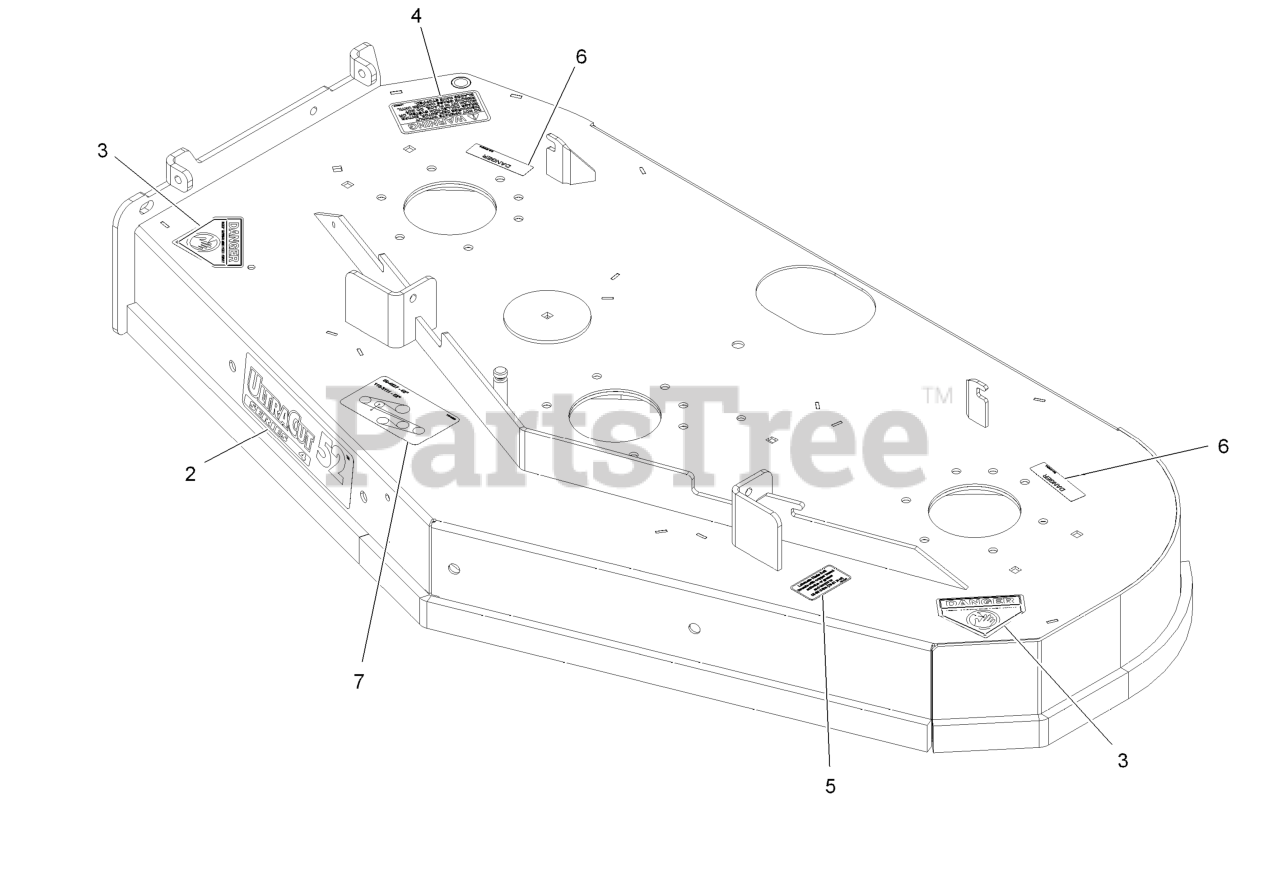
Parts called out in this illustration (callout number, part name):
2	DECAL,ULTRACUT 52 SERIES
3	DECAL-DANGER
4	DECAL-WARNING, DISCHARGE
5	DECAL,BOLT TORQUE
6	DECAL-COVER, MISSING
7	DECAL-BELT ROUTING
